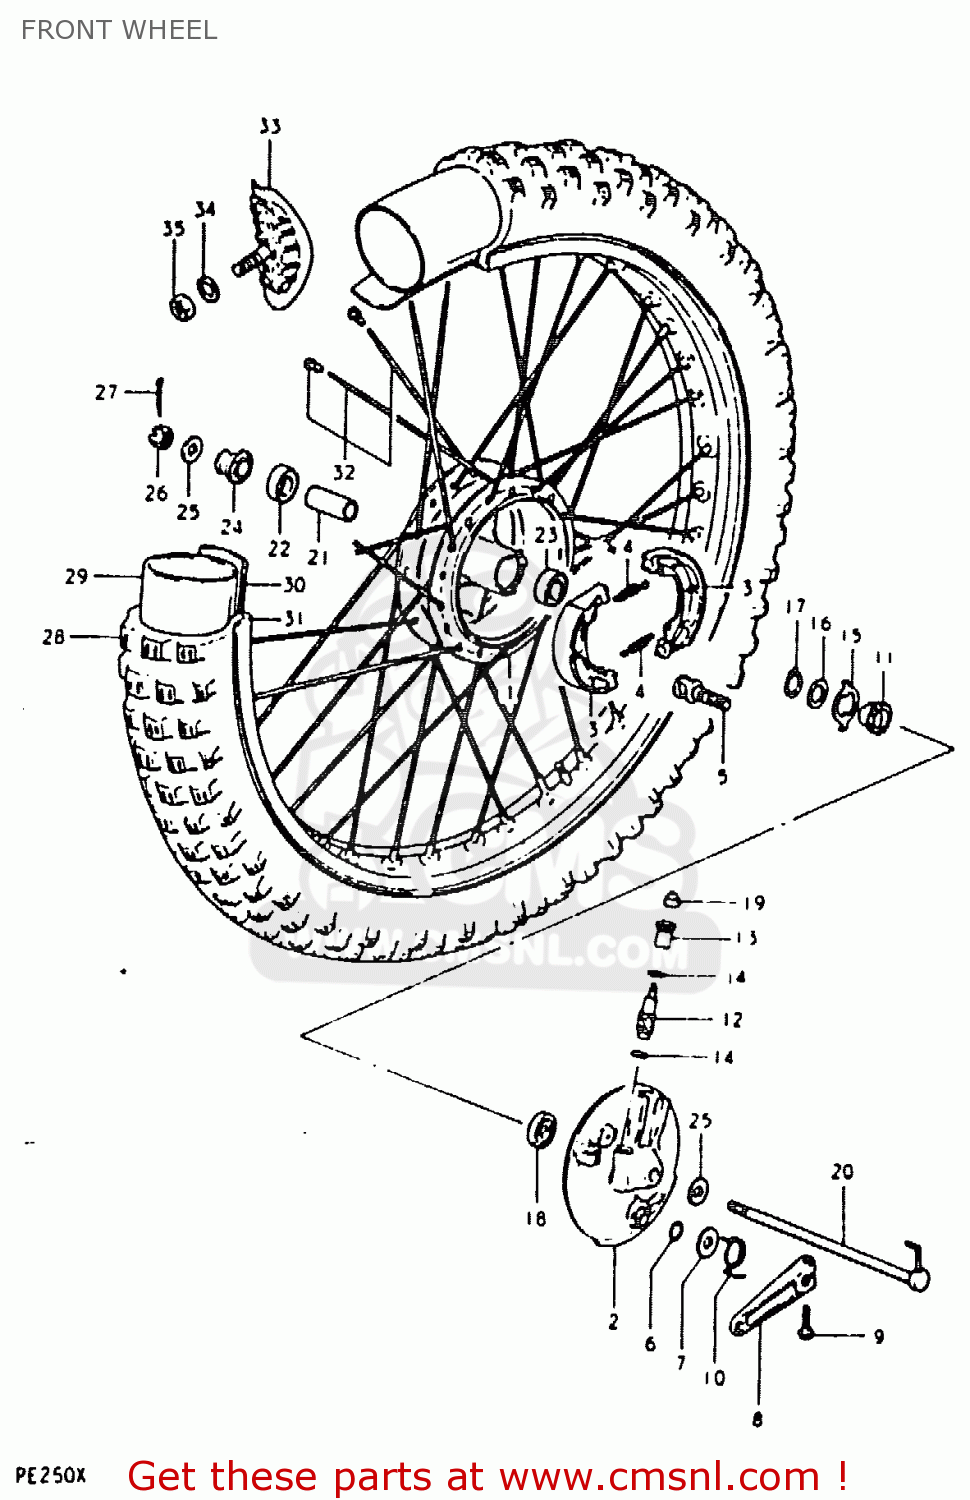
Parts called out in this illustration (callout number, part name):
1	DRUM,FRONT HUB
2	PANEL,FRONT HUB
3	SHOE,BRAKE
4	SPRING
5	CAM,FRONT BRAKE
6	O-RING,BOSS
7	WASHER (15X24X1.6)
8	LEVER,FRONT BRAKE CAM
9	BOLT
10	SPRING
11	GEAR,SPEEDOMETER
12	PINION,SPEEDOMETER
13	BUSHING,SPEEDOMETER PINION
14	WASHER (5.1X9X0.4)
15	DRIVER,SPEEDOMETER GEAR
16	WASHER(22.5X27X1)
17	CIRCLIP
18	SEAL,OIL(26X38X4)
19	SEAL,OIL(6X10X3)
20	AXLE,FRONT
21	SPACER (12.6X19X52)
22	BEARING, RH
23	BEARING
24	SPACER,FRONT AXLE,RIGHT
25	WASHER
26	NUT, REAR AXLE
27	COTTER PIN
28	TIRE,FRONT
29	TUBE,INNER
30	PROTECTOR,WHEEL,INNER
31	RIM,FRONT WHEEL
32	SPOKE SET,FRONT
33	STOPPER,BEAD
34	WASHER
35	NUT
